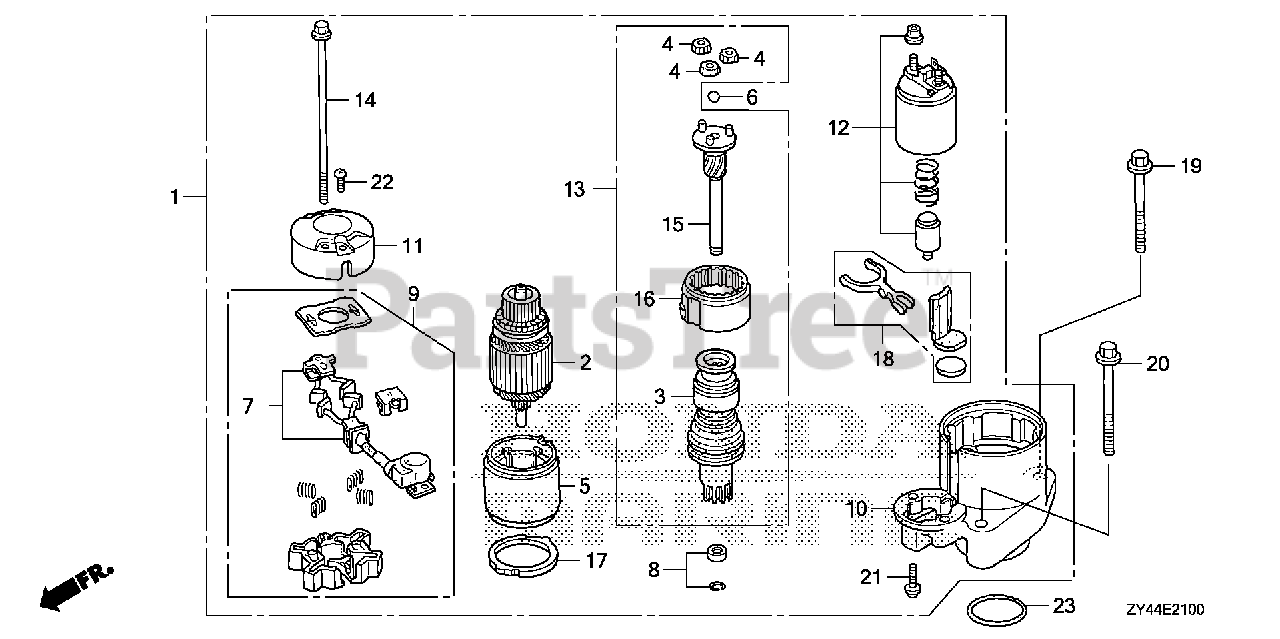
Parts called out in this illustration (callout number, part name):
1	STARTER MOTOR ASSY.
3	CLUTCH, OVERRUNNING
4	GEAR ASSY., PLANETARY
6	BALL, STEEL
8	STOPPER SET, SLEEVE
9	HOLDER, BRUSH
10	BRACKET, FR.
11	BRACKET, RR.
12	SWITCH ASSY., MAGNET
13	SHAFT ASSY., CLUTCH
14	BOLT A, THROUGH
15	SHAFT ASSY., GEAR
16	GEAR ASSY. (INNER)
19	BOLT, FLANGE (10X90)
20	BOLT, FLANGE (10X110)
21	SCREW, PAN (6X22) (SPECIAL)
22	SCREW, PAN (5X8)
23	O-RING (59.4X3.1)
